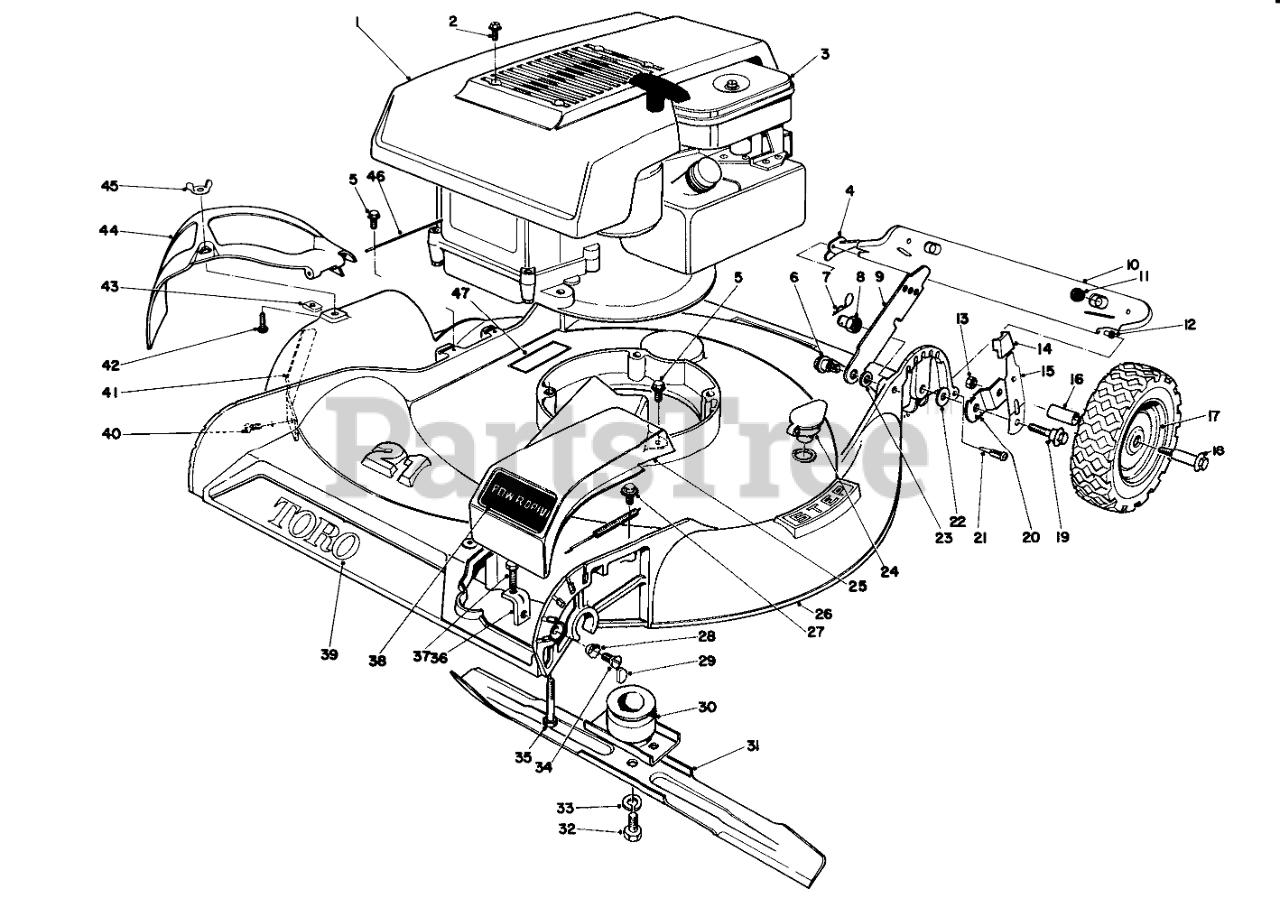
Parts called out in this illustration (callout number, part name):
1	Shroud
2	8X1/2 SELF TAP SCREW
3	Engine
4	Restraint R.H.
5	SCREW
6	SCREW-SHOULDER
7	PIN-COTTER, HAIR
8	HANDLE PIVOT NUT
9	Latch
10	Rear Safety Shield (Incl. Ref. Nos. 11 and 12)
11	SKID BUTTON
12	SAFTEY SHIELD BUSHING
13	Nut
14	Arm Knob
15	Spring Arm
16	Bushing
17	Rear Wheel with Tire (Incl. Ref. No. 16)
19	PIVOT SCREW
20	PIVOT ARM PLATED
21	SAFTEY SHIELD SCREW
22	WASHER-PIVOT
23	SPACER
24	WASHOUT PLUG
25	Guard, Belt
26	Housing
27	SCREW-HWHTF
28	Lockwasher
29	KEY-WOODRUFF
30	BLADE RETAINER WA
31	Blade
32	SPECIAL SCREW
33	WASHER-LOCK
34	5/16-18X5/8 FLT HD MS
35	3/8-16 X 2-3/4 CAPSCR
36	ADJ BRACKET
37	SCREW-HH
38	Decal Power Drive
39	Decal Toro
40	SCREW-HWH
41	Bar Safety
43	NUT-SPEED
44	Deflector
45	NUT-WING SPECL
46	HINGE PIN
47	Decal
